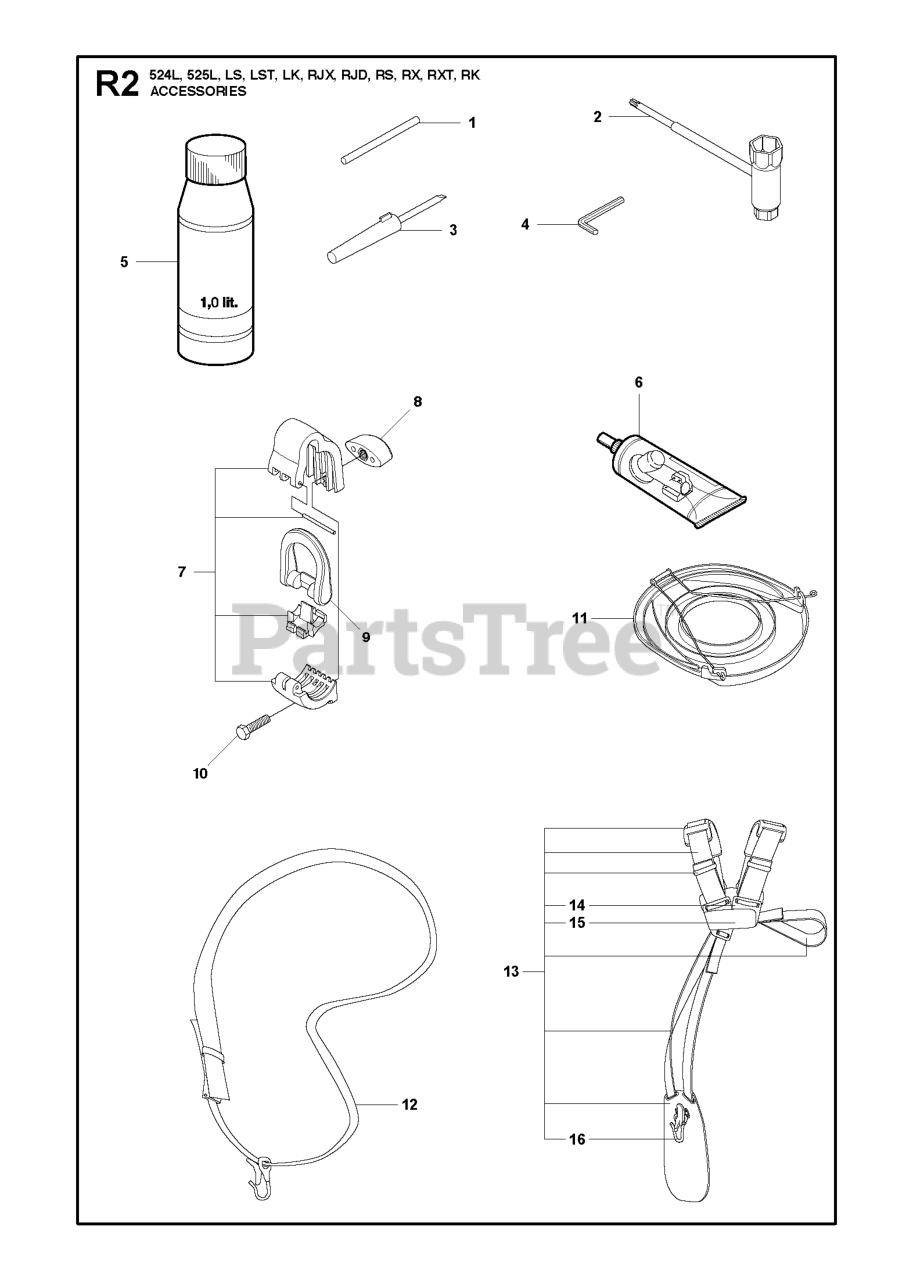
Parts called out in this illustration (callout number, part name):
1	LOCKING PIN
2	COMBINATION WRENCH TORX
3	SCREWDRIVER
4	L-KEY WRENCH
5	Air Filter Oil 1l.
6	BEVEL GEAR GREASE
7	HANGING BRACKET
10	SCREW M6S 5X20
11	BLADE GUARD TRANSPORT
12	Harness-w/o warning
12	Harness - Diagonal with sign
13	Harness w/warning
13	HARNESS DUO
16	HOOK, CPL.
